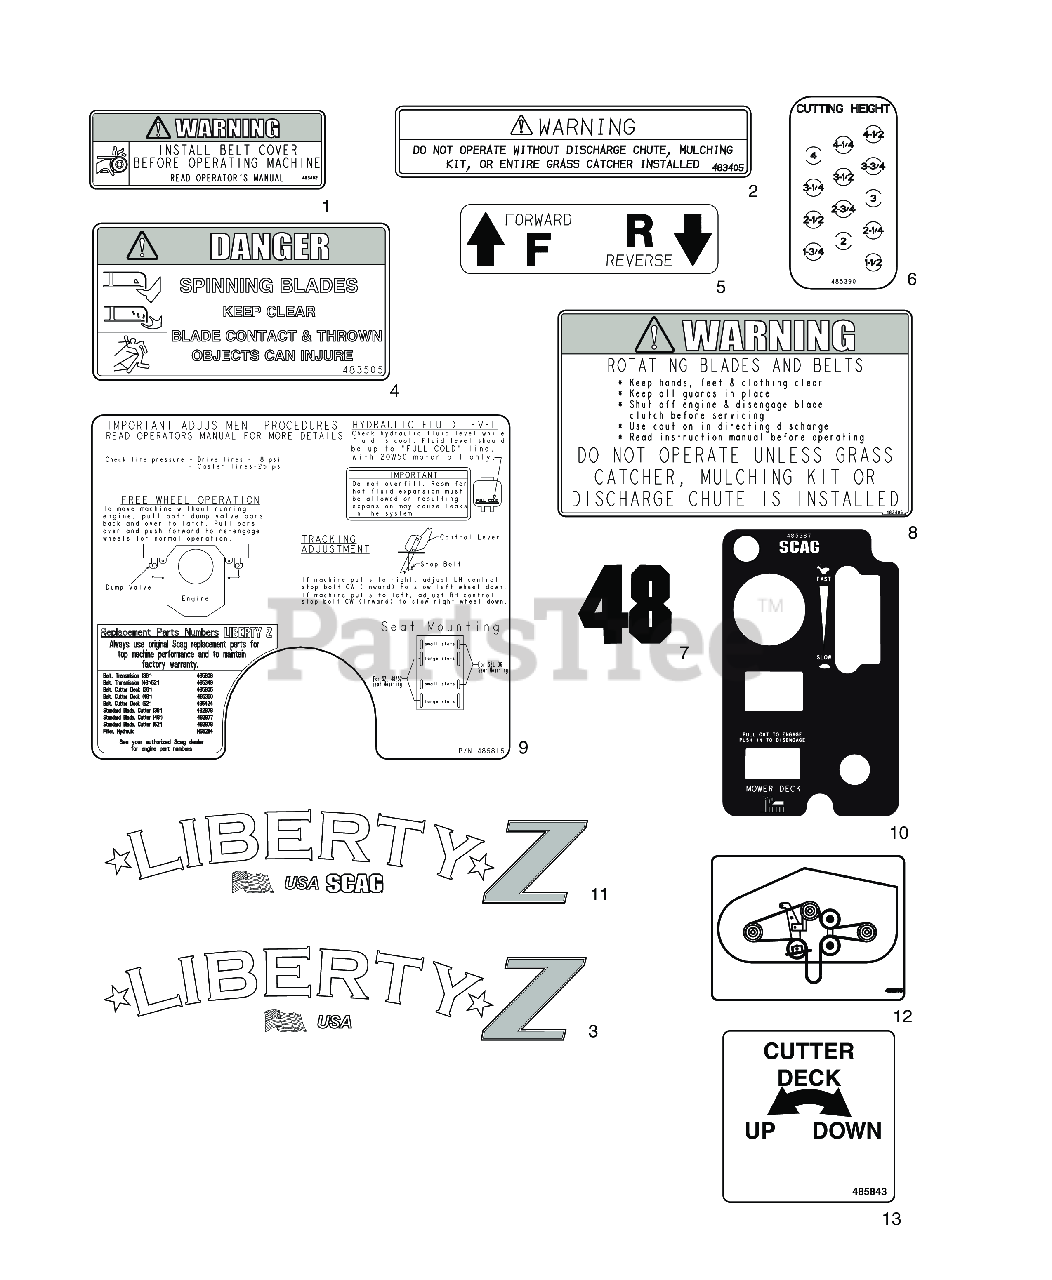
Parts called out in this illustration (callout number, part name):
1	Decal, Warning - Belt Cover
2	Decal, Warning-Discharge
3	Decal, Liberty Z - Bumper
4	Decal, Spinning Blades
5	Decal, Traction Control
6	Decal, Height of Cut
7	Decal, 36 Commercial
7	Decal, 48" Cutter Deck
7	Decal, 52" Cutter Deck
7	A-Decal-61
8	Decal, Warning - Rotating Blades
9	Decal, Adjustments - SZL
10	Decal, Instrument Panel - SZL (36)
10	Decal, Instrument Panel - SZL (48 & 52)
11	Decal. Liberty Z - Fuel Tank
12	Decal, Belt Routing - SZL (36)
12	Decal, SZL / SFZ / SPZ Belt Routing
13	Decal, Cutter Deck Lift Control
